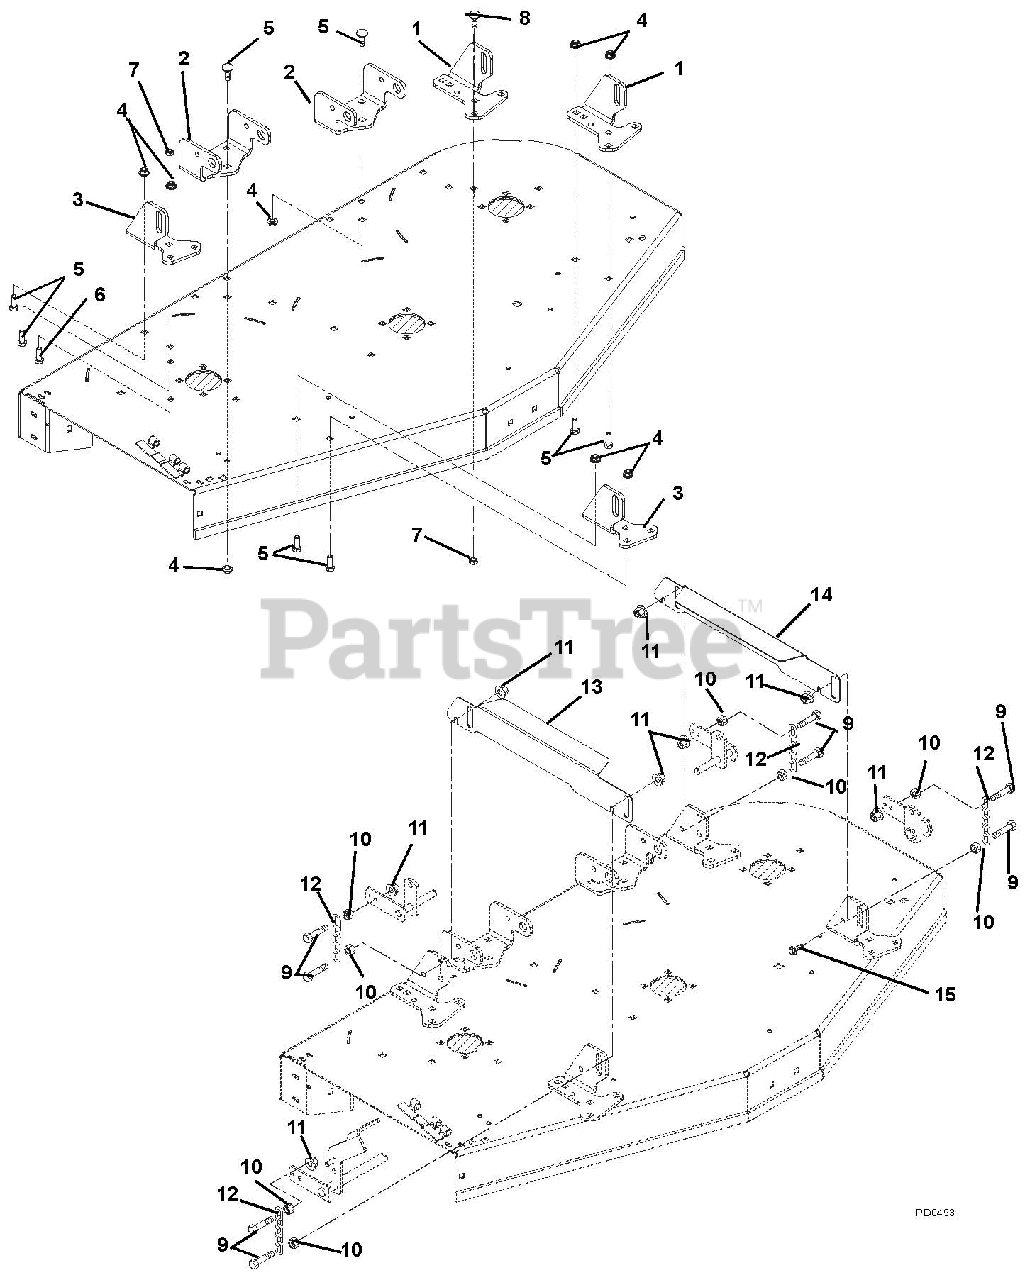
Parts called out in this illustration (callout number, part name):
1	Bracket, Deck Hanging
2	Bracket, Deck Mounting
3	Bracket, Deck Hanging
4	Nut, .38-16 Flange Nyloc
5	Bolt, Round Head Square Neck .38-16 x 1.00 Grade 5
6	Bolt, Round Head Square Neck .38-16 x 1.25 Grade 5
7	Nut, Locking Jam .375-16
8	Bolt, Round Head Square Neck .38-16 x .75 Grade 5
9	Bolt, Hex M12-1.75 x 55 Grade 5
10	Nut, Spinlock Flange M12-1.75
11	Nut, Locking Top Flange M12-1.75
12	Chain, Link
13	Bracket, Deck Stabilizing RH
14	Bracket, Deck Stabilizing LH
15	Screw, Tapping .25-20 x .50 Hex Washer Head
